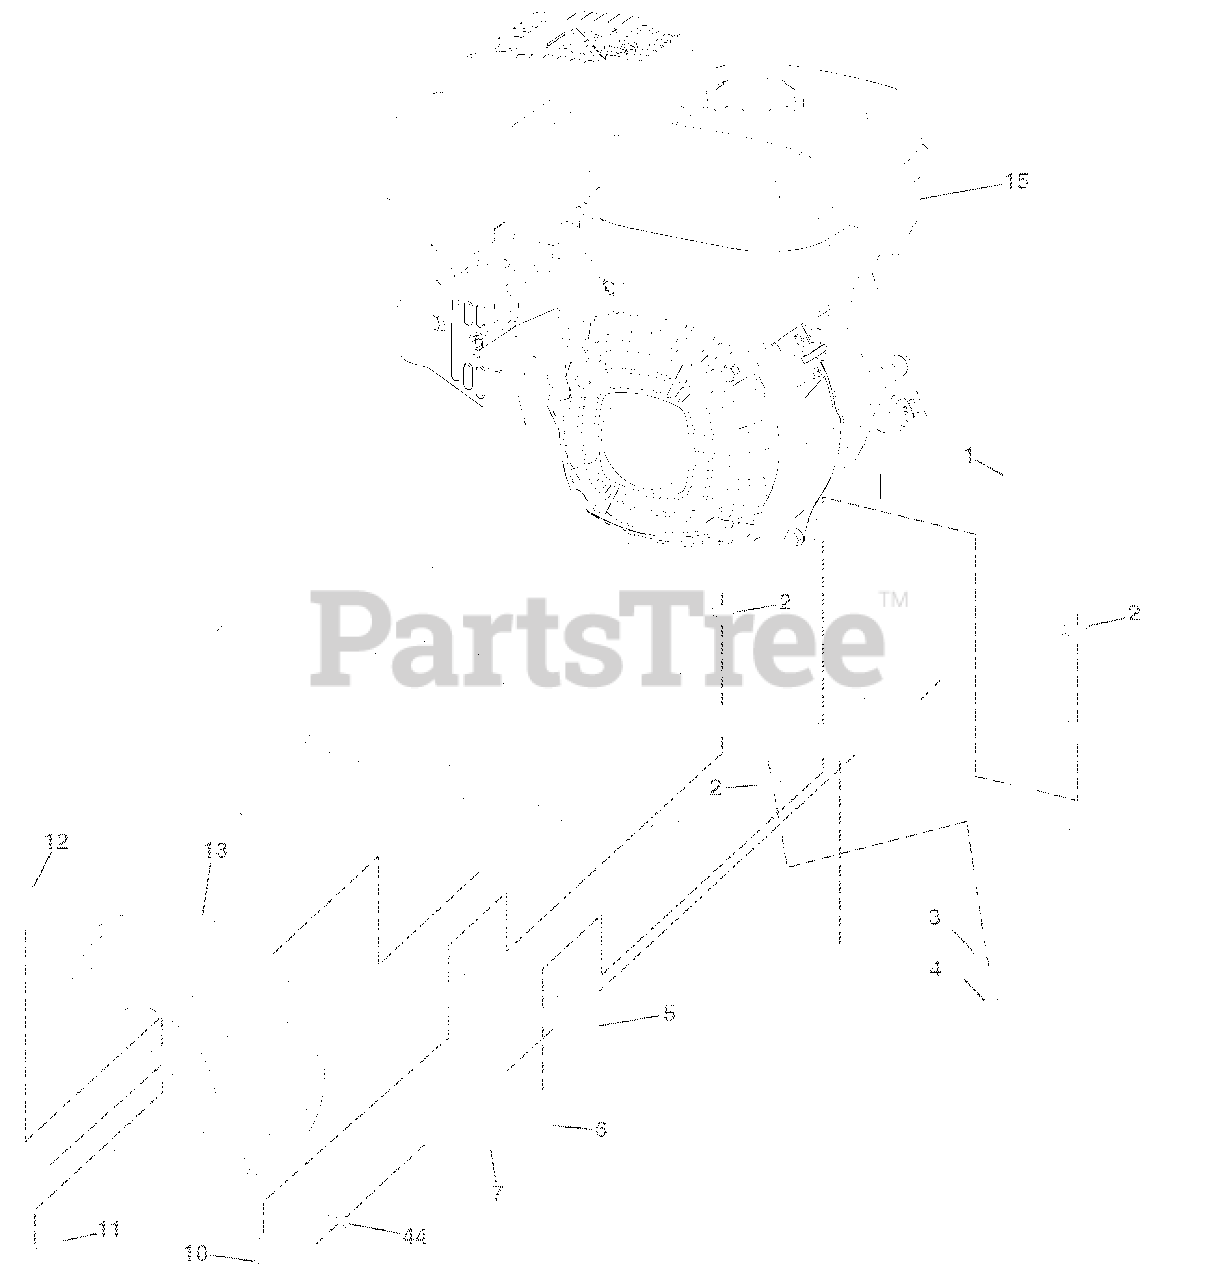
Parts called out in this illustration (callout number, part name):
2	Nut, Hex, Flangelock
3	Washer 11/32 x 11/16 x 16 Ga.
4	Bolt, Hex Head 5/16-18 x 3/4
5	Bracket, Reinforcement
7	Counter Weight, RH
10	Bolt, Hex Head, Gr. 25/16-18 x
11	Retainer Spring
12	Rivet, Drilled
22	Bolt, Fin Hex 5/16-18 unc x 1-
44	Nut Keps Hex 3/8-16 unc
